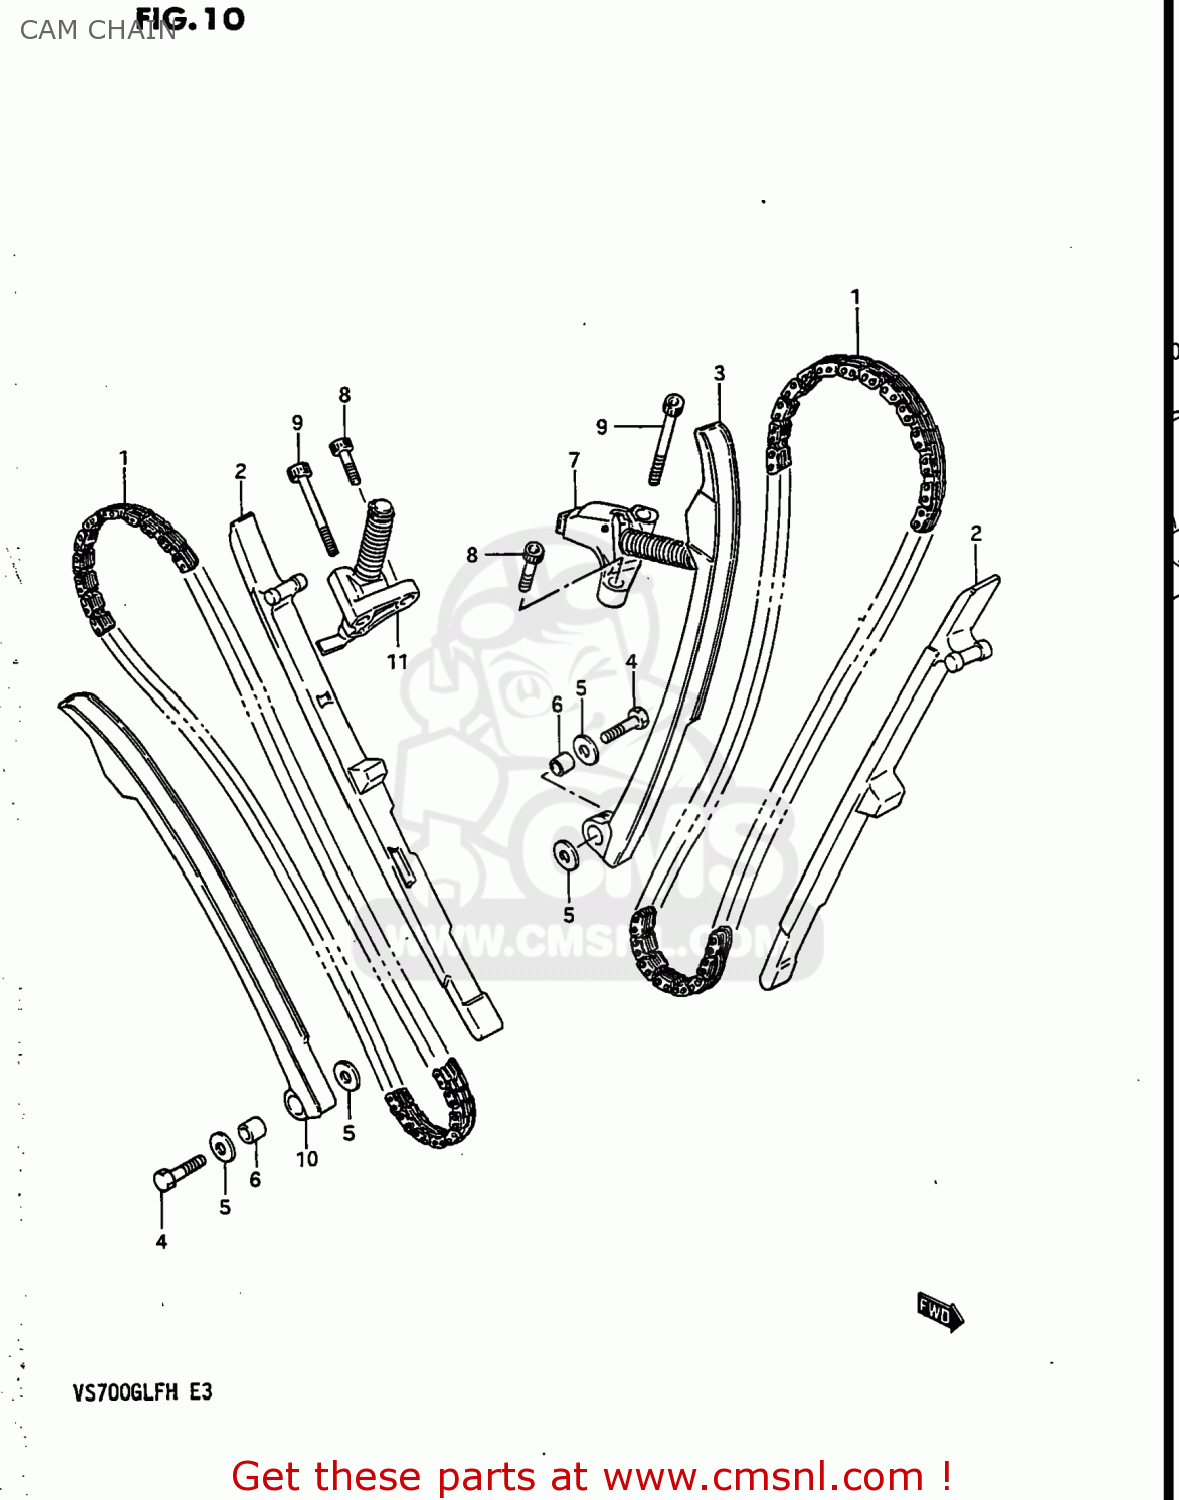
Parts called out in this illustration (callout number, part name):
1	CHAIN,CAMSHAFT DRIVE
2	GUIDE,CAM CHAIN
3	TENSIONER,FR CAM CHAIN
4	BOLT(6X26)
5	WASHER
6	SPACER(6X11X11)
7	ADJUSTER ASSEMBLY,FRONT TENSIONER
8	BOLT
9	BOLT
10	TENSIONER,RR CAM CHAIN
11	ADJUSTER ASSEMBLY,REAR TENSIONER
